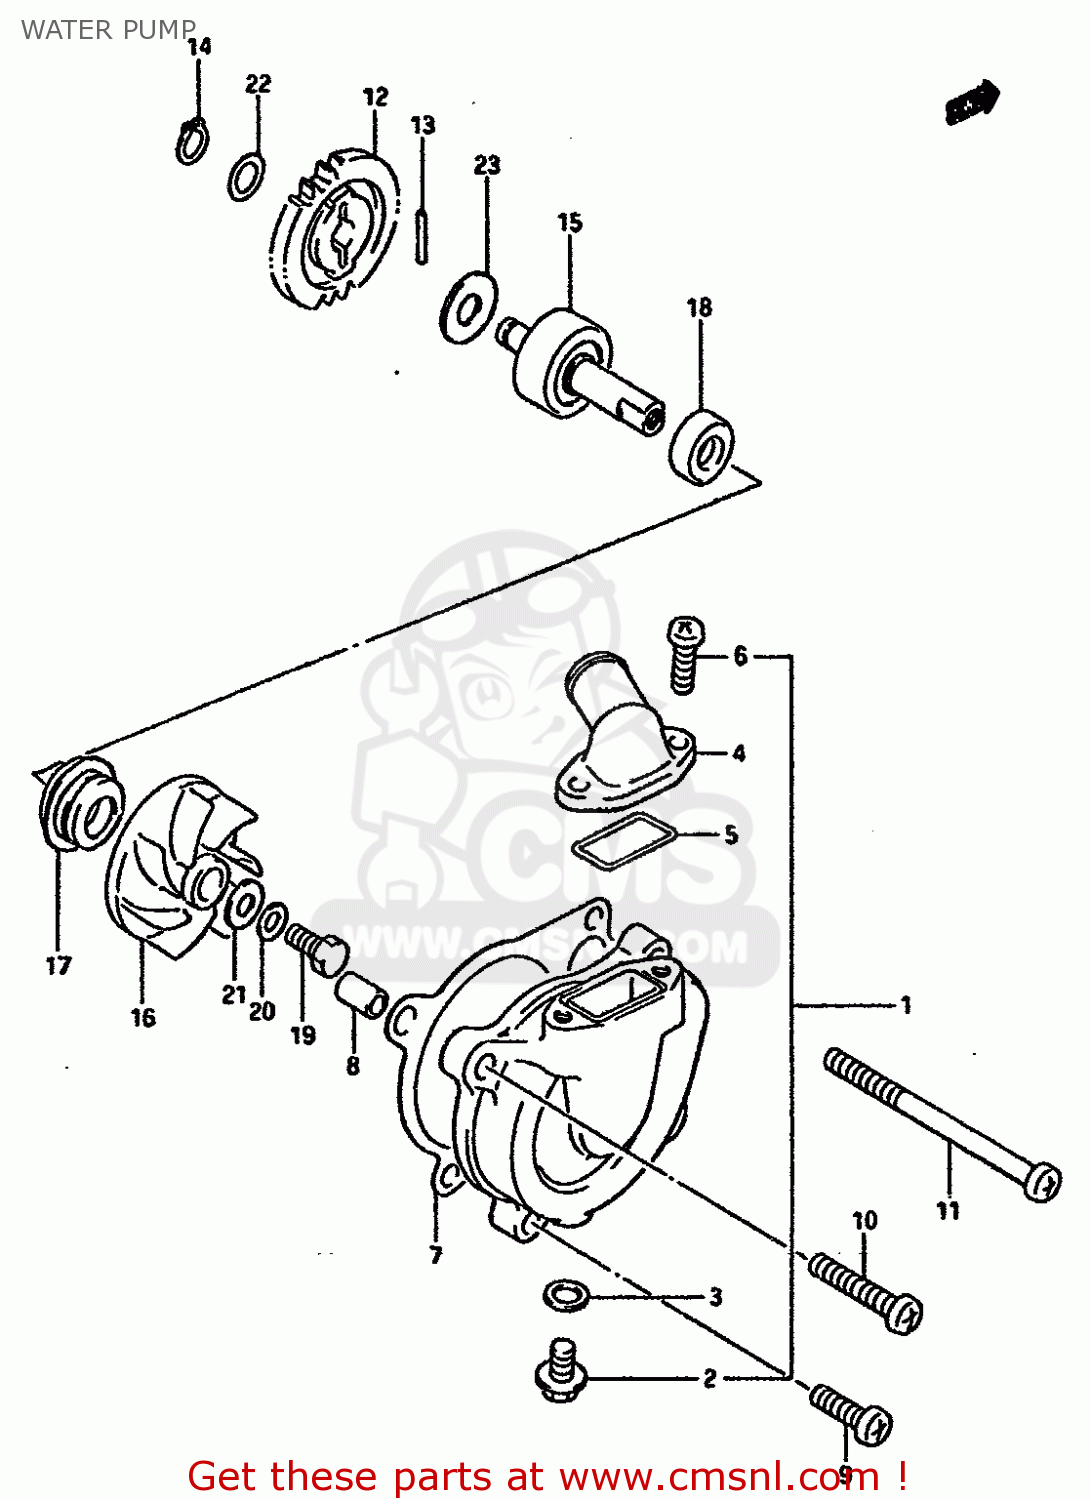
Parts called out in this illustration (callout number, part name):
1	CASE,WATER PUMP
2	BOLT,DRAIN
3	GASKET 8.2X14X1 (NAS)
4	CONNECTOR
5	O RING,WATER PUMP CONNECTOR
6	SCREW
7	GASKET,WATER PUMP CASE (MCA)
8	PIN
9	SCREW
10	SCREW
11	SCREW (6*75)
12	GEAR,WATER PUMP DRIVEN
13	PIN(2.5X19.8)
14	CIRCLIP
15	SHAFT,WATER PUMP
16	IMPELLER,WATER PUMP
17	SEAL,WATER PUMP SHAFT
18	SEAL,OIL(10X20X5)
19	BOLT(6X13)
20	WASHER
21	GASKET(6X15X2.2) (NAS)
22	WASHER
23	WASHER
